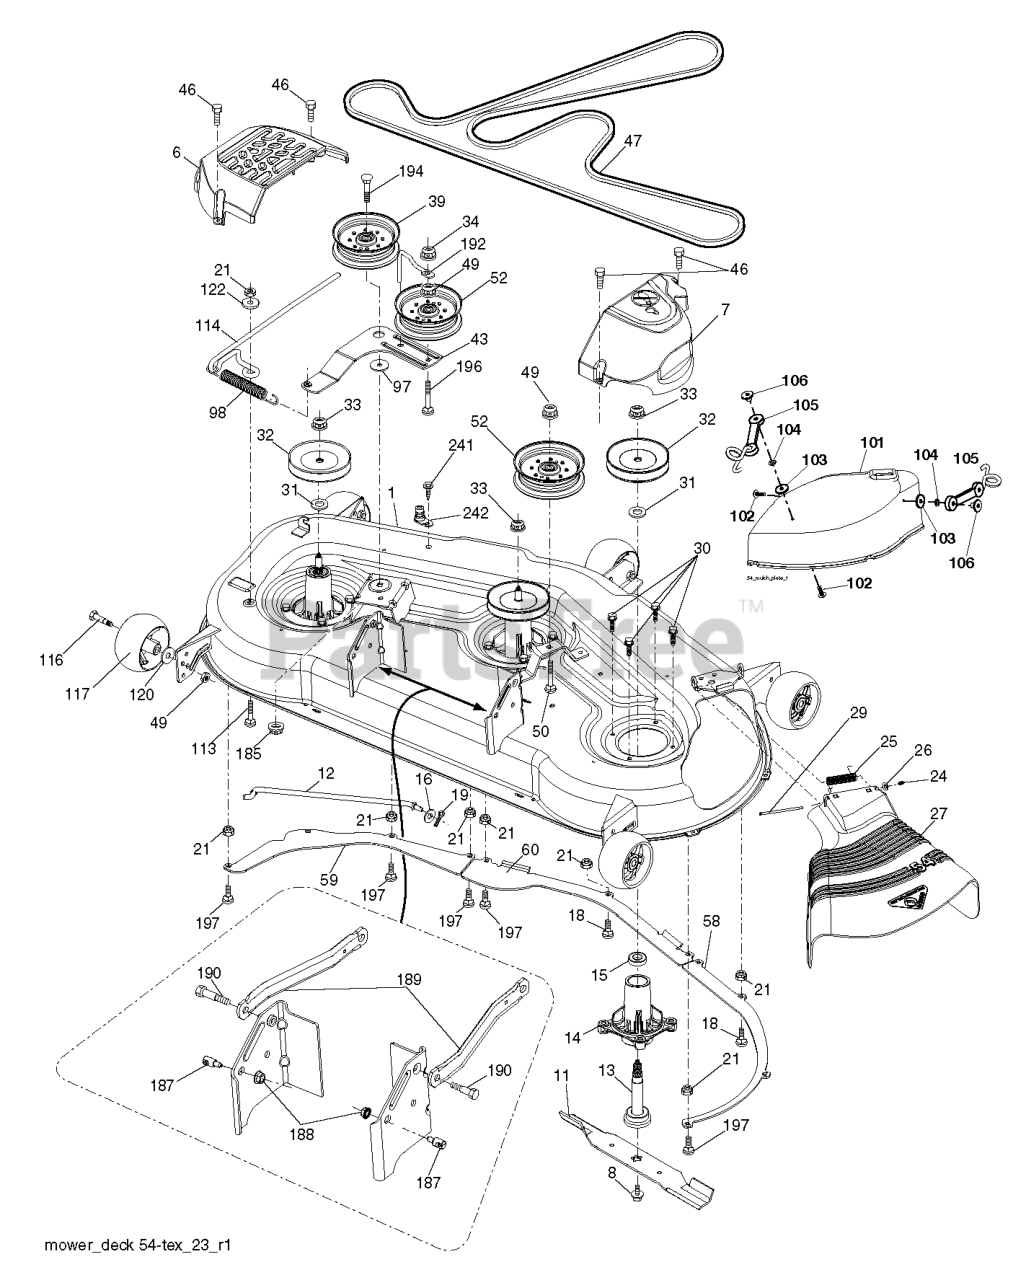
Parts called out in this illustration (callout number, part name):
1	DECK.WLDMT.W/TUBES.54".ORANGE
6	COVER.MANDREL.LH.54"20
7	COVER.MANDREL.RH.54.20
8	BOLT.WASHER.ASM.7/16-2
11	BLADE.BAGGING.54"
11	54" MULCH BLADE
12	ROD.ANTI.SWAY.48/54"K4
13	SHAFT ASM MANDREL
14	RP.HOUSING.MANDREL.4PT.
16	WASHER
18	BOLT
19	PIN.COTTER.5/16.BOW TI
21	LOCKNUT
24	CAP-SLEEVE LT
25	SPRING, TORSION
26	NUT PUSH M
27	DEFLECTOR
29	ROD.HINGE
30	SCREW, WASHER HEAD
31	WASHER.SPACER.MANDREL
32	PULLEY/MANDREL
33	NUT.FLANGE.LOCK.TOP
39	RB PULLEY.IDLER.4.50/HUB SPEC
43	ARM.IDLER
46	SCREW.1/4-20X5/8
47	RP.BELT.DRIVE.54."2006
49	NUT LOCK FLG 3/8-16 UNC
50	BOLT
52	PULLEY.IDLER.2006
58	BAFFLE.RIGHT.54"
59	BAFFLE.LEFT.54"
60	BAFFLE CENTER 54" MOWER
98	SPRING, DECK DRIVE
101	MULCH COVER 54"
102	SCREW
104	LOCKWASHER #10
105	LATCH ASSY
106	WELDNUT
113	BOLT CRT
114	ROD TENSION RELIEF
116	BOLT.SHOULDER.3/8-16X3-5/8.
117	RP WHEEL. GUAGE RALLY
120	WASHER
122	BUSHING.RELIEF.TENSION
185	NUT.LOCK.FLANGE.7/16
187	STUD.FASTNER.W/ANTI-ROTATE
188	NUT LOCK HEX FLANGE 5/16-18
189	ARM.SUSPENSION.MOWER
190	BOLT.SHOULDER
192	KEEPER.BELT.IDLER.54"T
194	BOLT.HEX.WASHER.HEAD.7/16-24X
196	BOLT
197	BOLT
241	SCREW.TT.#10-32X.5.3/8.FLANGE
242	PORT.WASHOUT
